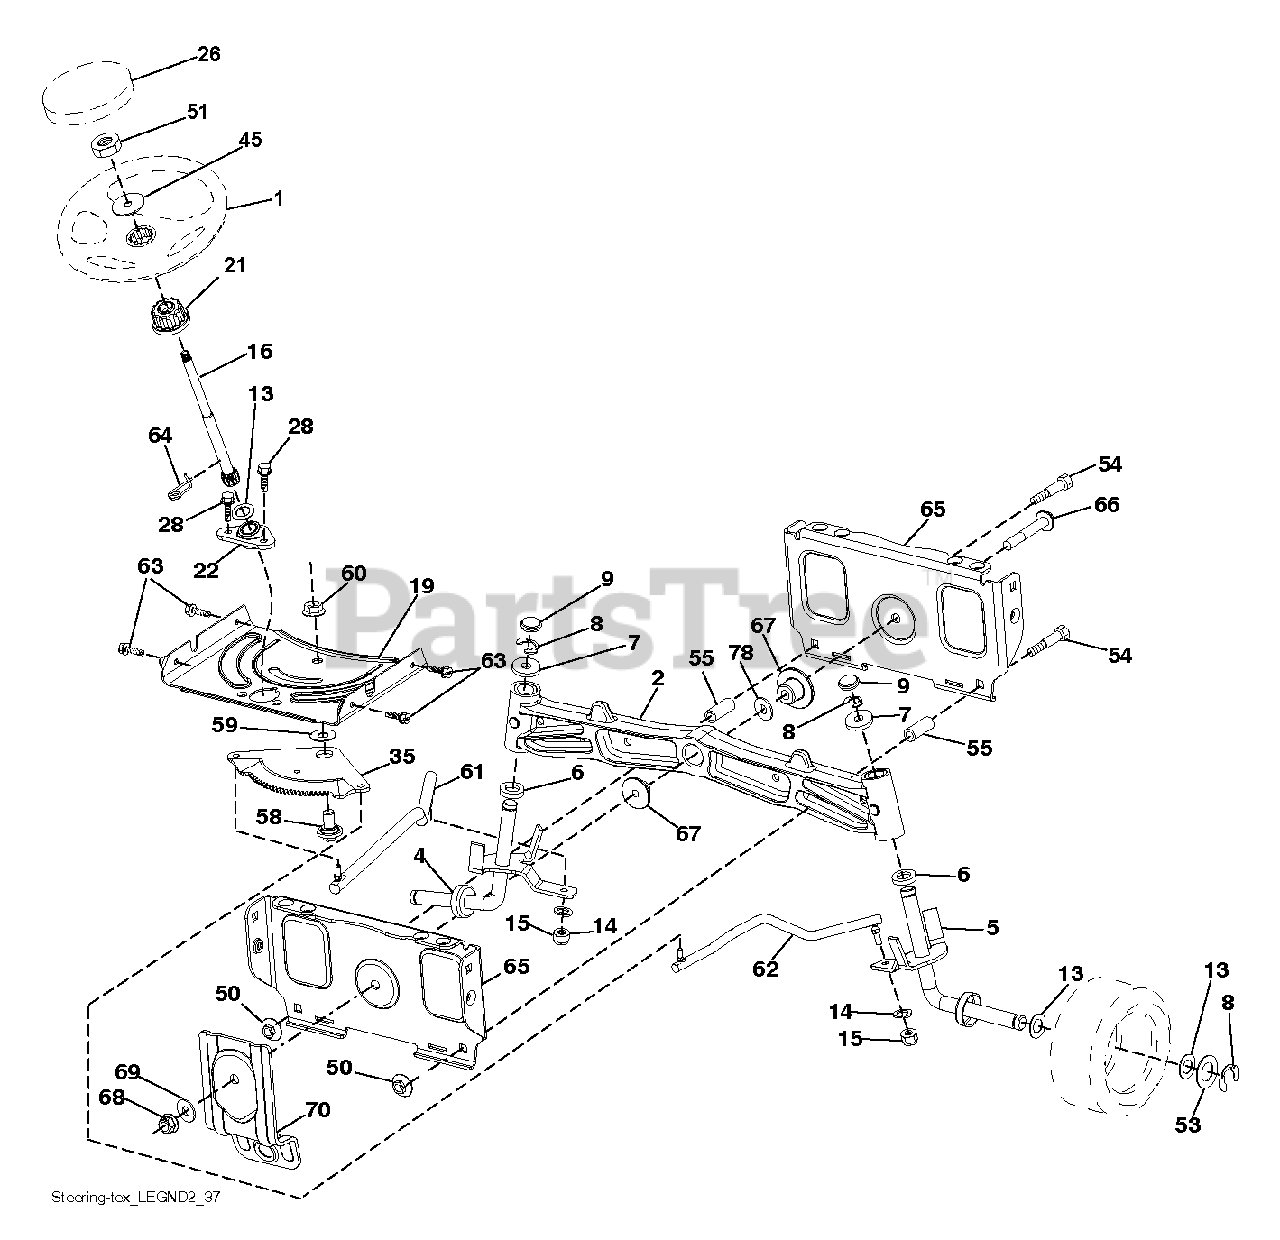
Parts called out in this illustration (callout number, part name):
1	RP WHEEL.STEER.HUSQ.PREM.OVMLD
2	AXLE.CAST.IRON
4	SPINDLE.WELDED.LH.16"TEX
5	SPINDLE.WELDED.RH.16"TEX
6	THRUST WASHER
9	CAP.SPINDLE.BLACK
14	WASHER, LOCK 3/8
15	NUT CROWNLOCK 3/8-24
16	SHAFT, STEERING
19	PLATE.STEER.DDL.NLT/NG
21	ADAPTER, WHEEL STNG..
22	STEERING.SUPT.LOWER.
26	RP INSERT.CAP.WHL.STRG.HUSQ.
28	SCREW, 3/8-16X3/4
35	GEAR.SECTOR.PLATE.DDL.
45	WASHER 9/16"ID, 2 3/8"OD
50	NUT LOCK FLG 3/8-16 UNC
51	NUT.HEX.1/2-20
53	WASHER.HARDENED
55	SPACER.BRACE.AXLE
58	BOLT.SHOULDER.SECTOR.P
59	WASHER.THURST.SECTOR.S
60	NUT FLANGE LOCK 5/8-11
61	DRAGLINK.LH.BALLSTUD.D
62	DRAGLINK.RH.BALLSTUD.D
63	SCREW
64	RETAINER.CLIP.SPRING.S
65	BRACE.AXLE.FRONT.NLT/N
66	BOLT HEX FGHD 7/16-14 X 3 SERR
67	BUSHING.PM.FRONT AXLE
68	NUT.LOCK.FLANGE.7/16
69	WASHER.1.5X.505X.118
70	BRKT.DECK.SUSPENSION.F
78	THRUST WASHER
